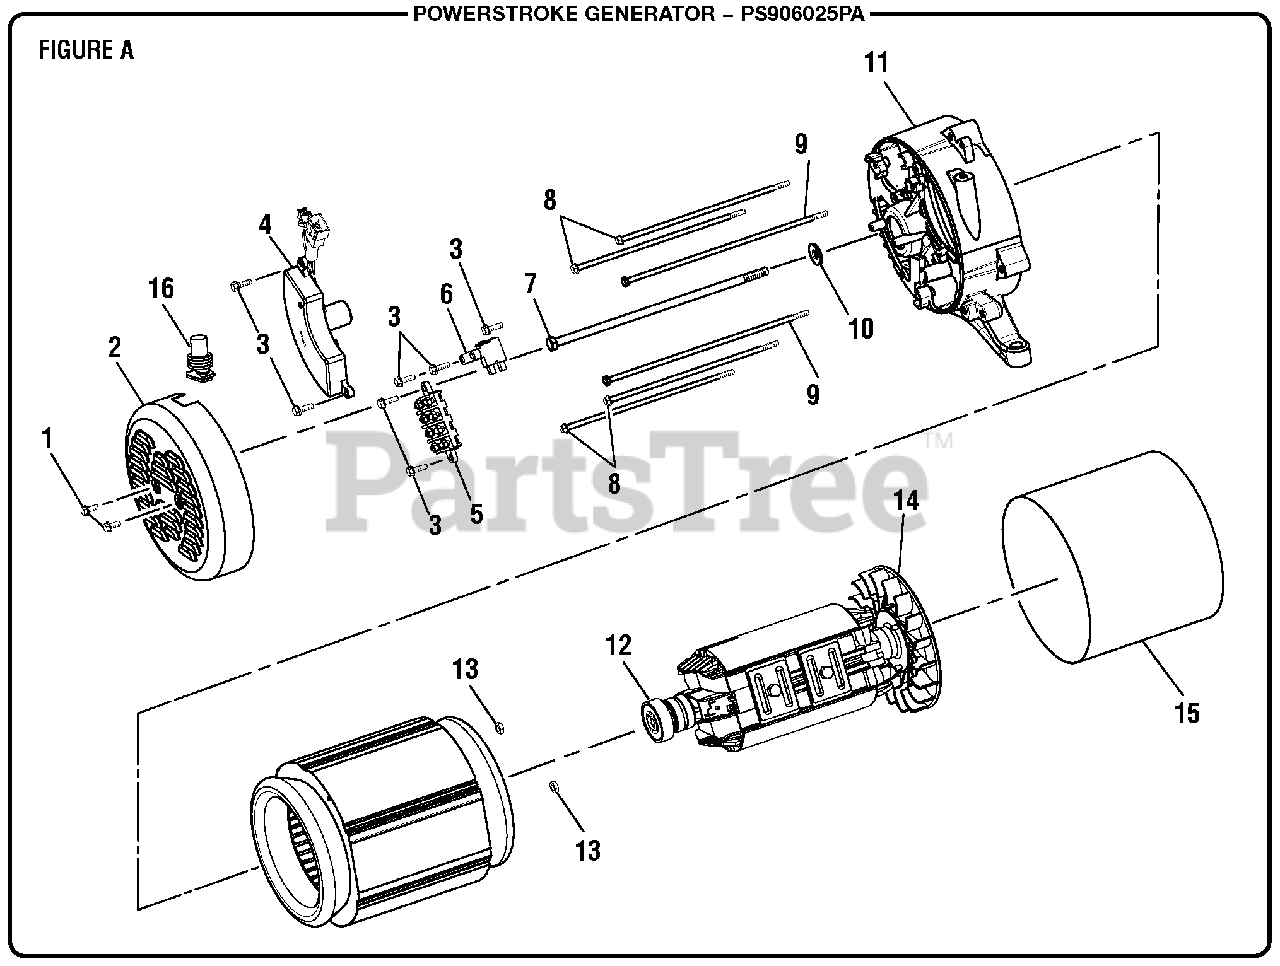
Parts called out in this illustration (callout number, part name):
1	Bolt (M5 x 12 mm, Hex Hd.)
2	Brush Cover
3	Bolt (M5 x 16 mm, Hex Hd.)
4	Automatic Voltage Regulator
5	Terminal Block
6	Brush Assembly Kit
7	Rotor Bolt
8	Stator Bolt
9	Bolt (M5 x 230 mm, Hex Hd.)
10	Washer (5/16 in.)
11	Bearing Housing'
12	Ball Bearing
13	Hex Nut (M5)
15	Generator Head Cover
16	Rubber Boot
